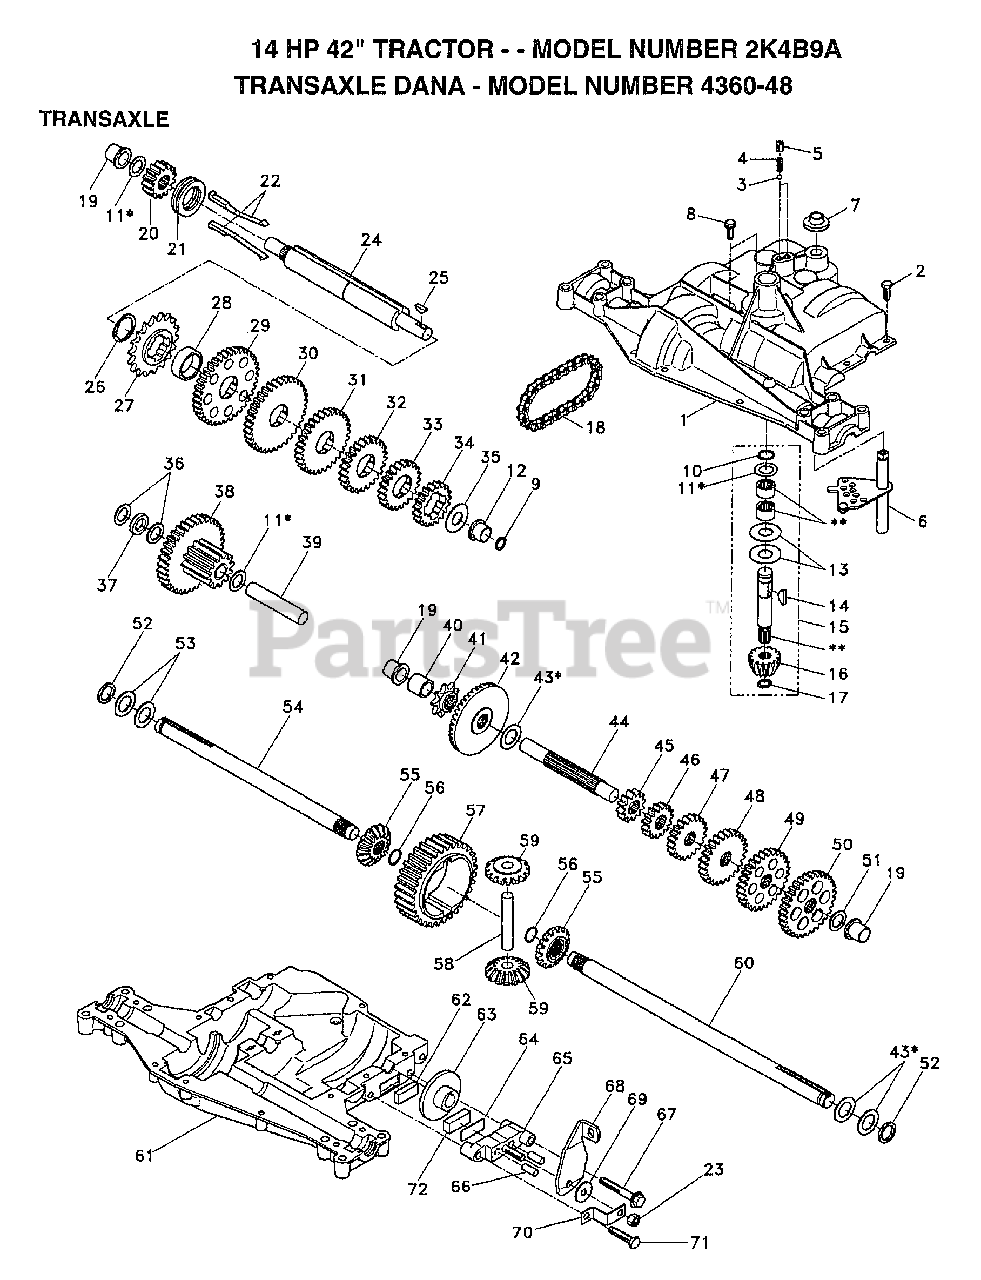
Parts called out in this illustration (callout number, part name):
4	"SPRING, DETENT LT"
5	"SCREW, SET LT"
6	KIT SHIFTER ASM
7	SHIFTER BOOT
8	SCREW TAP W/SEAL
9	SQUARE RING
10	RETAINING RING LT
11	ASM KIT SHIM 4689
12	"FLANGE, BEARING"
13	WASHER T
14	WOODRUFF KEY
15	AS KIT INPUT SHFT
16	PINION 14T T
17	"RING,RETAINING LT"
18	"CHAIN,24 PTCH LT"
19	BEARING.FLNG.5510
20	GEAR SPUR 14T
21	COLLAR CLUTCH
22	ASM KIT CLTCH KEY
23	NUT.LOCK.5/16-24
24	SHAFT INTERM
25	WOODRUFF KEY
26	"RING,RETAINING LT"
27	SPROCKET 18T T
28	SPACER YT
29	KIT.GEAR.12/37TH
32	GEAR 25T LT
33	GEAR SPUR 22 TT
34	SPUR GEAR 19T
35	"WASHER, PLAIN LT"
36	WASHER 025
37	SPACER
38	ASSM GEAR COMB
39	SHAFT IDLER
40	SPACER T
41	SPROCKET 9T LT
43	ASM KIT SHIM
44	SHAFT T
48	"GEAR, SPUR 25T LT"
49	GEAR 28T T
50	"GEAR, SPUR 31T LT"
51	WASHER 060
52	NEOPRENE WASHER
53	WASHER 031
55	GEAR 15T T
56	"RING,RETAINING LT"
58	SHAFT T
59	GEAR 1ST T
62	PUCK T
63	BRAKE DISC. T
64	SPACER LT
66	PIN T
69	WASHER LT
71	"SCREW, TAPPING LT"
72	PUCK T
